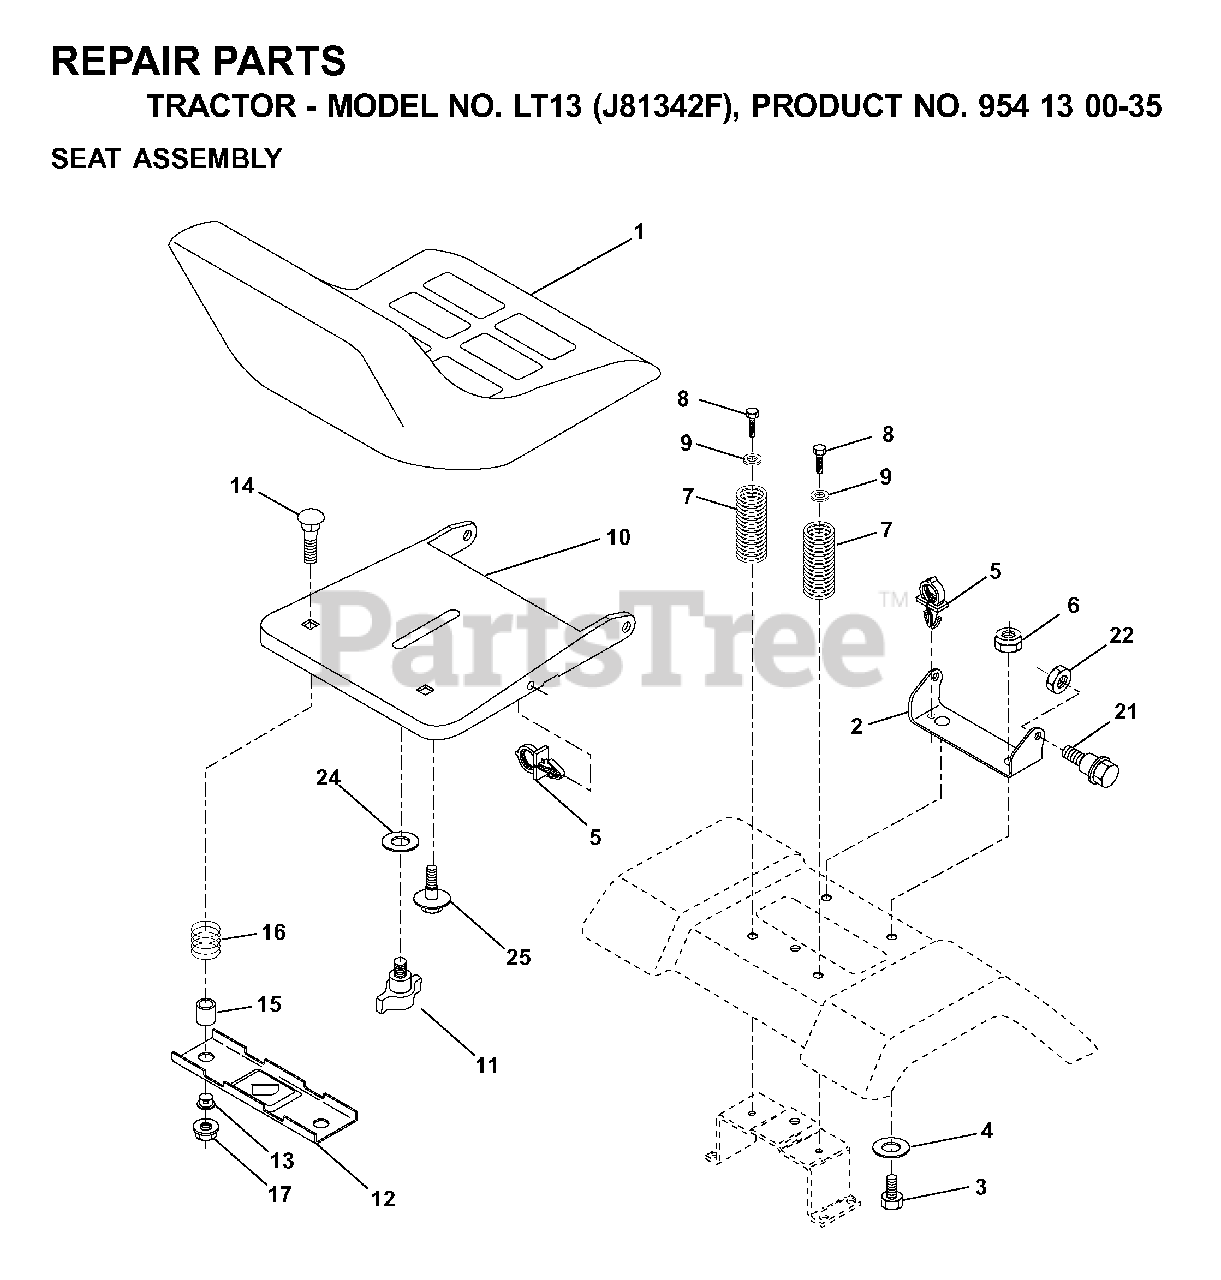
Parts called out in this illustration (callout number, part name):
2	SEAT PIVOT BRKT
4	WASHER PM
5	PUSH CLIP
6	NUT
7	SPRING COMPRESSION
8	SCREW 3/8-16X1
9	WASHER
10	PAN, SEAT
11	KNOB.SEAT.ADJ.WINGNUT
12	BRKT SWITCH
14	BOLT.ROUND.HEAD.SQUARE.NECK
15	SPACER SPLIT 28X.96
17	NUT T
21	BOLT.SHOULDER.5/16-18
22	NUT.71038.31-18.HEX.NYLOCK
25	BOLT,SHOULD
